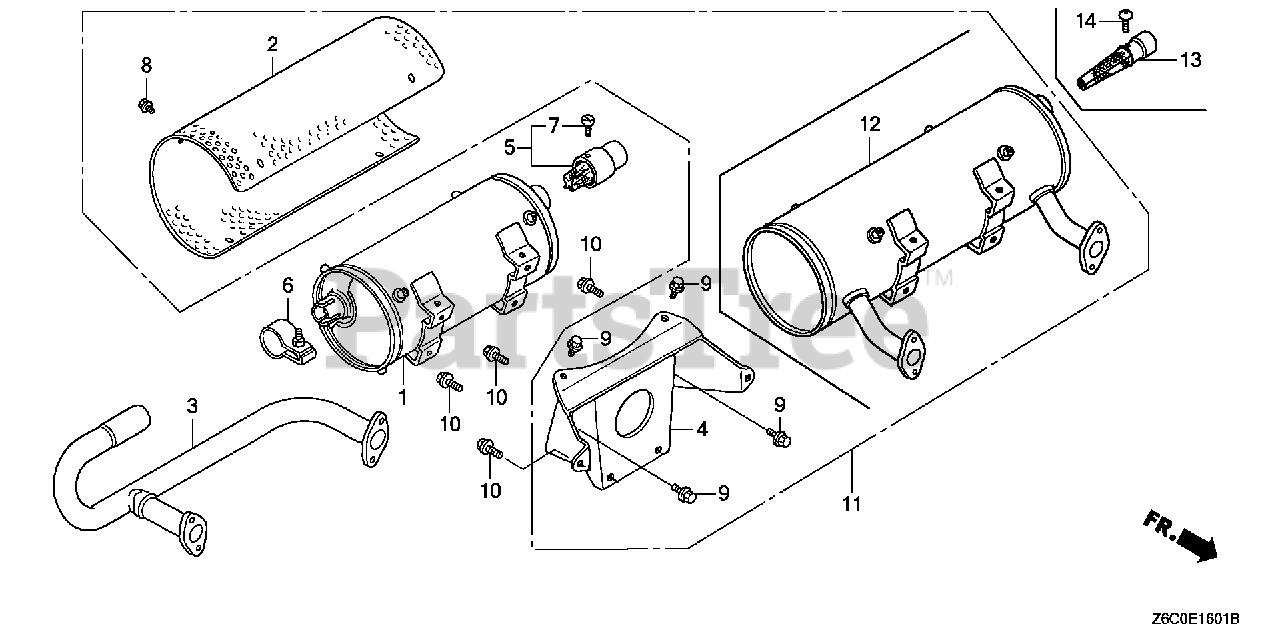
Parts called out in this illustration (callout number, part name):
1	MUFFLER (HIGH)(NELSON)(BLACK MUFFLER) (SHIFT18300-ZJ1-891) (IF N/A - #18300-ZJ1-891 LT.)
2	PROTECTOR, MUFFLER (HIGH) (FUTABA) (FOR BLACK MUFFLER)
2	PROTECTOR, MUFFLER (HIGH) (FUTABA) (FOR SILVER MUFFLER)
3	PIPE, EX. (HIGH-L) (FOR BLACK MUFFLER)
4	STAY, MUFFLER (HIGH-FUTABA) (FOR SILVER MUFFLER)
4	STAY, MUFFLER (HIGH-NELSON) (FOR BLACK MUFFLER)
5	ARRESTER, SPARK (FOR BLACK MUFFLER)
6	BAND ASSY. (FOR BLACK MUFFLER) (NOT AVAILABLE)
7	SCREW (NELSON) (FOR BLACK MUFFLER)
8	BOLT, FLANGE (6X8) (FOR SILVER MUFFLER)
9	BOLT, FLANGE (8X14) (FOR SILVER MUFFLER)
10	BOLT, FLANGE (8X20)
11	MUFFLER ASSY. (HIGH-L) (FUTABA) (SILVER MUFFLER) (FOR SILVER MUFFLER)
12	MUFFLER COMP. (HIGH-L) (FUTABA) (SILVER MUFFLER) (FOR SILVER MUFFLER)
13	ARRESTER KIT (HIGH)
13	ARRESTER, SPARK (FOR SILVER MUFFLER)
14	SCREW, TAPPING (5X8) (FOR SILVER MUFFLER)
